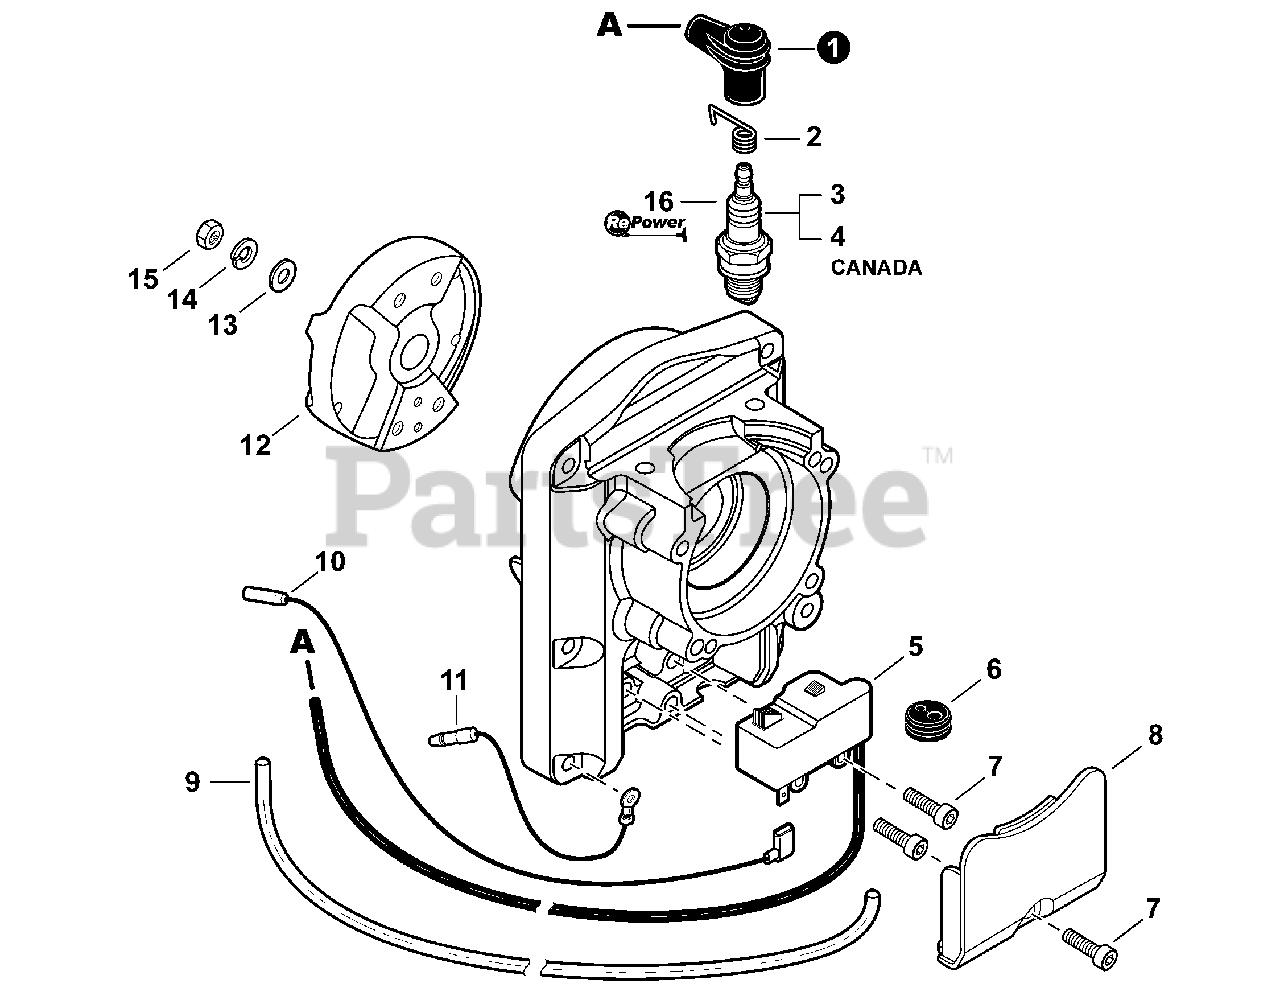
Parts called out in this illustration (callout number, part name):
1	CAP, SPARK PLUG
2	TERMINAL, SPARK PLUG
3	SPARK PLUG - BPM8Y
4	SPARK PLUG - BPMR8Y
5	COIL, IGNITION
7	BOLT, TORX 5×16
8	COVER, DUST
10	LEAD - IGNITION
11	LEAD - GROUND
12	FLYWHEEL
13	WASHER, SPRING 10
14	WASHER, SPRING 10
16	TUNE-UP KIT - REPOWER
